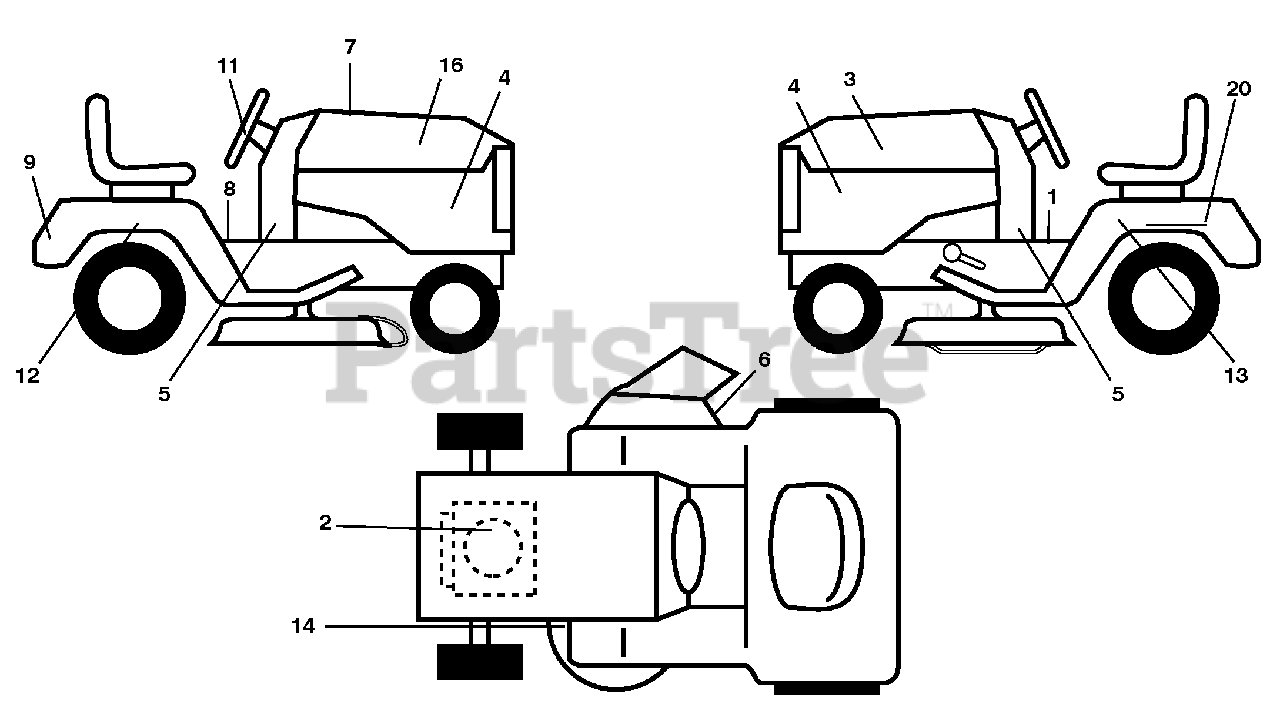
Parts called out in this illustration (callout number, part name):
2	Decal Eng. H.P.
3	Decal Hood LH
4	Decal Side Panel Logo
5	Decal Lwr Dash
6	Decal Warning, Keep Hand Away
7	Decal Replacement Parts
8	Decal Fender Warn S/F
9	Decal Fender Logo
11	Decal Ins Strg Whl
12	Decal Fend SD Rh
13	Decal Fend SD Lh
14	Decal V-Belt Schematic
16	Decal Hood Rh
20	Decal Bat Dan/Psn
20	Pad Footrest LH
20	Pad Footrest RH
20	Manual Operator's (Eng)
20	Manual Operator's (French)
